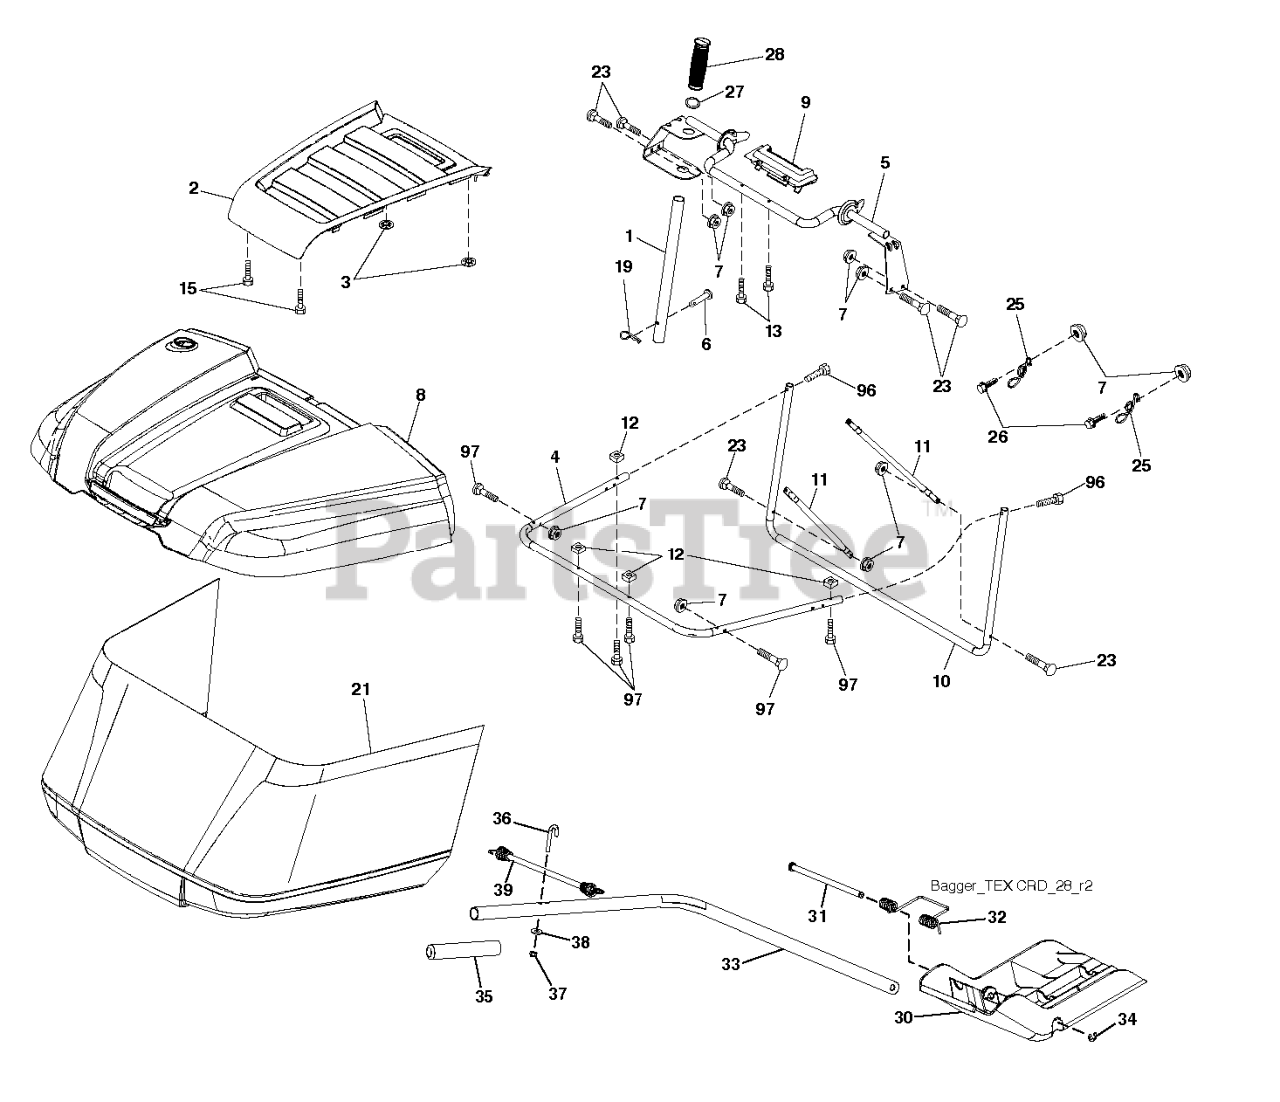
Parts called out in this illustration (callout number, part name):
1	TUBE.HANDLE.BAGGER.CRD/SRD.BLA
2	APPLIQUE.TOP.BAG.SRD.ORANGE
3	NUT.PUSH.156
4	SUBASM.TOP.BAGGER.TUBE
5	FRAME.ASM.TOP.BAGGER.SRD
6	RIVET,DRILLED
7	NUT T
8	BAGGER.TOP.SRD.APPLIQUE
9	INSERT.HANDLE.BAGGER.(2 2)
10	FRAME FRAME.FRONT.TEX.CRD
11	BRACE BRACE SIDE TUBE
12	NUT.SQUARE.1/4
13	SCREW.1/4X1.150.HXWSH
15	SCREW,#8.FLAT.HEAD.DRILL.TIP
19	PIN.COTTER.5/16.BOW TI
21	BAG SUBASM. TEX CRD GEN 2 HUSQ
25	SPRING.LATCH.BAGGER.SRD
26	SCREW HEX CRT
27	RB GROMMET.RUBBER.SRD
28	GRIP.HANDLE.BLACK
30	PLUG PLUG
31	PIN PIN.HINGE
32	SPRING SPRING DOUBLE TORSION
33	SHAFT SHAFT TEX CRD MULCH PLU
34	E-RING.5/16"
35	GRIP GRIP MULCH PLUG HAND
36	BOLT BOLT J
39	BUBGEE BUBGEE TEX CRD
96	SCREW.HEXCAP.1/4X-20X1.500
97	SCREW.TORX.BUTN.HD.1/4-20-1.5"
